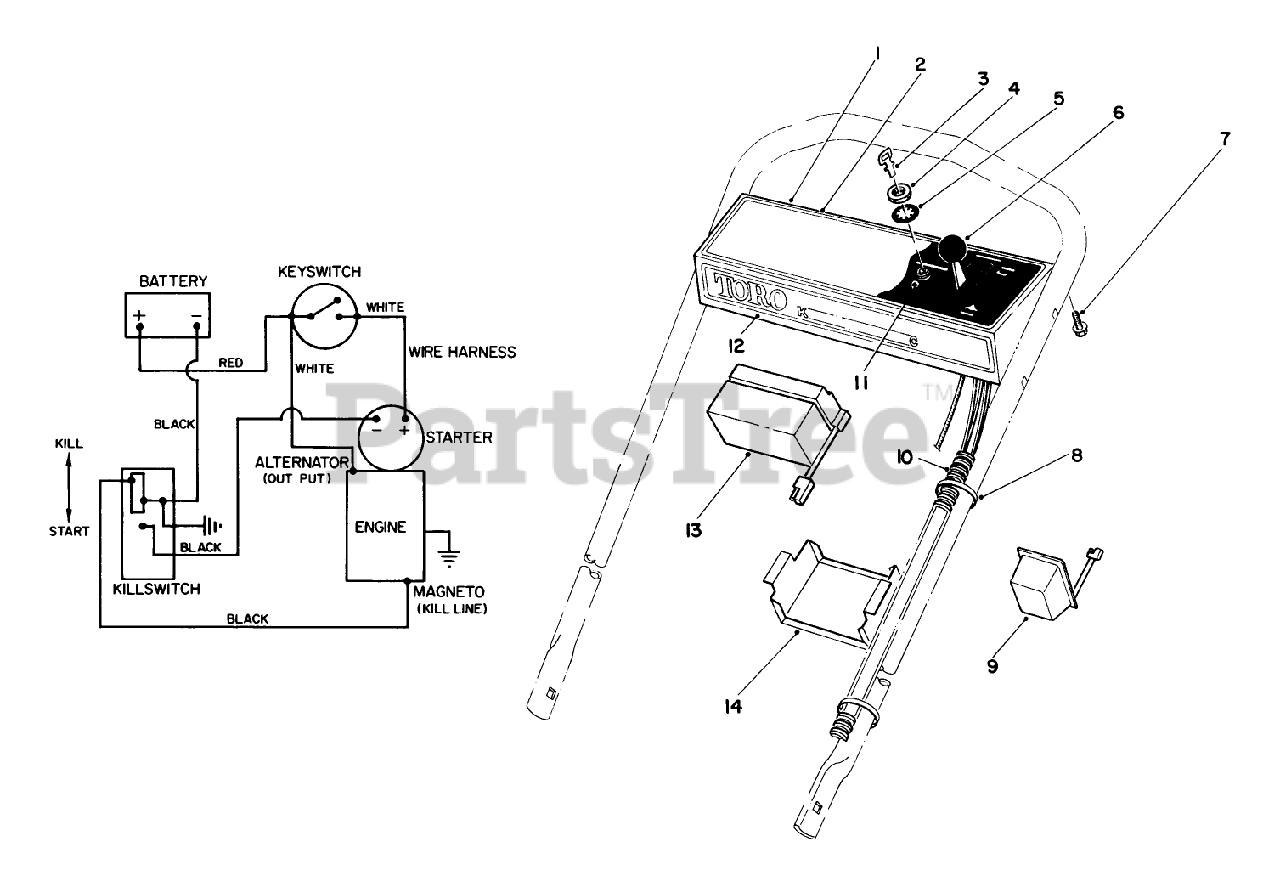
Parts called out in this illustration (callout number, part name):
3	KEY-IGNITION
4	NUT-HH
5	WASHER-LOCK
6	SERVICE THROTTLE CONTRO
7	SCREW-HWHTF
8	TIE-CABLE
10	WIRE HARNESS
11	STARTER SWITCH ASM
